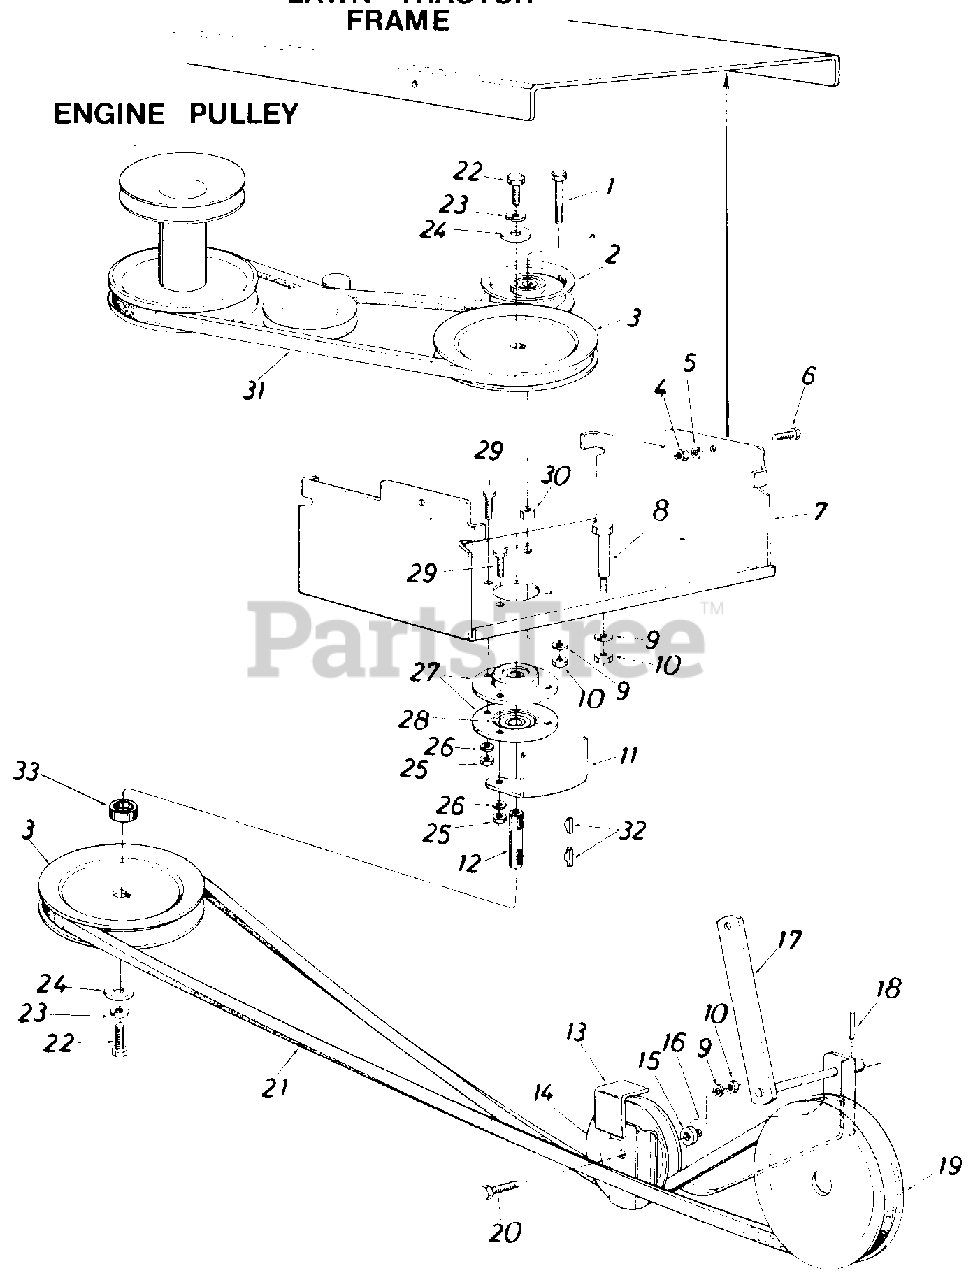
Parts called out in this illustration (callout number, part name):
1	Hex Bolt 3/8-16 x 2.00" Lg.
2	Fl.-Idler w/Flanges 3-3/4" O.D.
3	5/8" "V"-Pulley.790" I.D. x .650" O.D.
4	Hex Nut 3/8-24 Thd.
5	L.-Wash. 3/8" I.D. Heavy Duty
6	Hex Bolt 3/8-24 x .88" Lg.
7	Carriage Bracket
8	Shoulder Bolt .498" Dia. x 1.64
9	L.-Wash. 3/8" I.D.
10	Hex Nut 3/8-16 Thd.
13	Belt Separator Plate
14	Fl.-Idler w/Flanges 3.25" 0.D.
15	Fl.-Wash. .406" I.D. x 1.25" O.D. x .164
18	Spring Pin Roll 3/16" Dia. x 1.50" Lg.
19	`5/8" V-Pulley 1.50" I.D. x 6.50" O.D.
20	Hex Bolt 3/8-16 x 1.75" Lg.*.
21	"V"-Belt 1/2" x 95.0" Lg.
22	Hex Bolt 5/16-18 x .88" Lg. Spec.
23	L.-Wash. 5/16" I.D.
24	Fl.-Wash. .344" I.D. x 1.125" O.D. x .125
25	Hex Nut 5/16-18 Thd.
26	L.-Wash. 5/16" I.D.
27	Bearing Housing 1.85" I.D.
28	Ball Bearing .787" I.D. x 1.85" O.D.
29	Hex Sems Bolt 5/16-18 x .75"
30	Spacer
31	Belt 1/2" Wide x 52" Long
32	Hi-Pro Key 3/16" x 5/8"
33	Spacer-.80" I.D. x 1.O" O.D.
